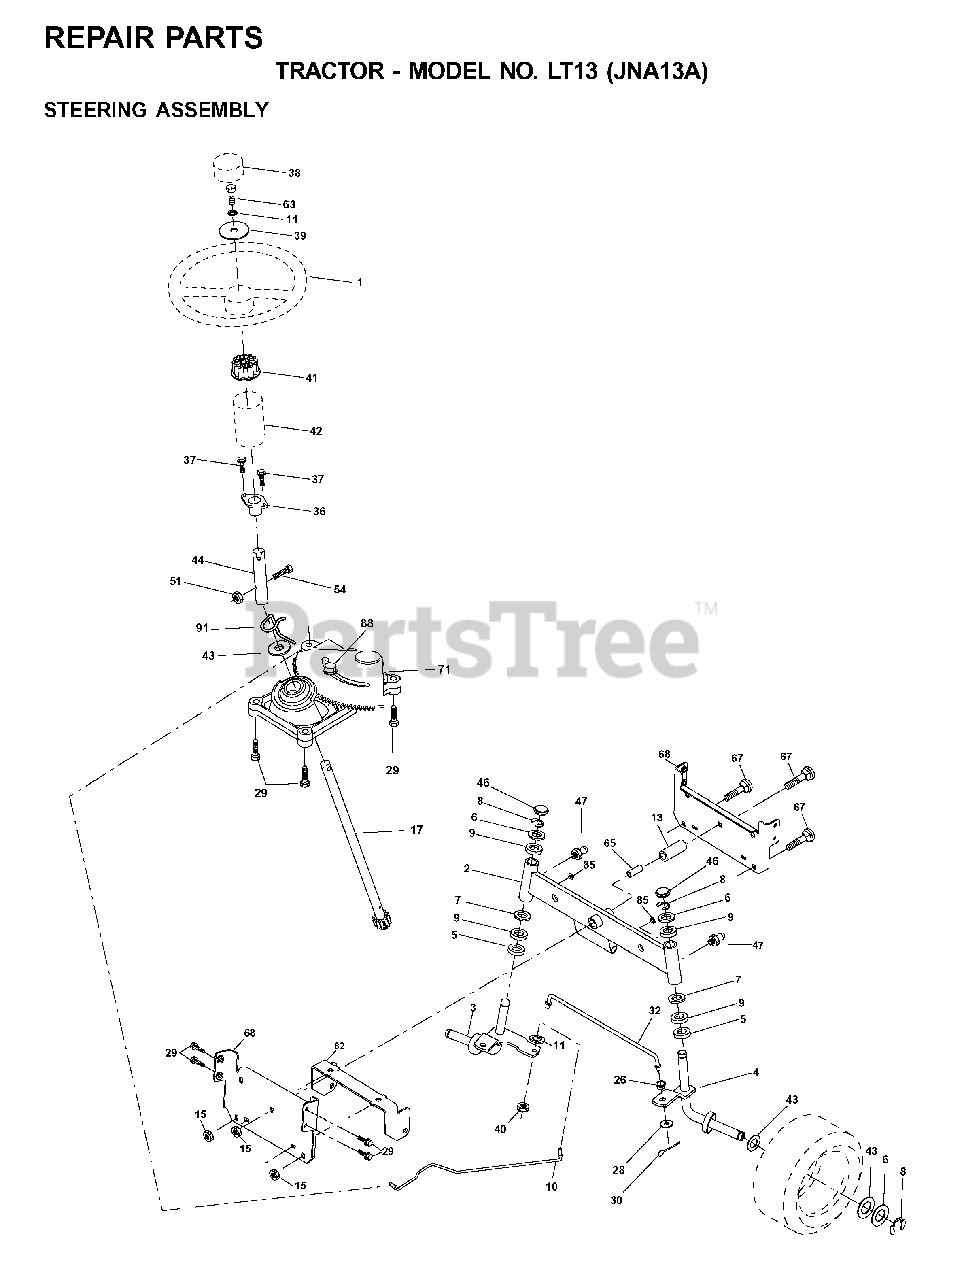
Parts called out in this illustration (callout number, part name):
2	AXLE ASSY
3	SPINDLE.ASM.LH.15"TIRES
4	SPINDLE.ASM.RH.15"TIRES
8	RING CLIP
9	BRNG T
10	DRAGLINK.15".TIRES.2001
11	WASHER, LOCK 3/8
13	TUBE, PIVOT AXLE
15	NUT
17	SHAFT ASM
26	BUSHING.DRAGLINK
28	WASHER
29	SCREW 3/8-16X3/4
30	COTTER PIN
32	TIE ROD
36	BUSHING, STEERING
39	WASHER 13/32 X 2-3/8 X 12GA
40	GRIPCO NUT
41	ADAPTER LT
42	BOOT.STEERING.SHAFT.BLACK
44	EXT SHAFT STEERING
46	CAP.SPINDLE
47	ZERK M
51	NUT.71038.31-18.HEX.NYLOCK
54	BOLT.5/16-18X1-1/4 FULL.THREAD
65	SPACER BRACE AXLE
67	BOLT
68	BRACE.AXLE.15"TIRES
71	STEERING ASM
82	BRACKET
85	FASTENER.XMAS.TREE
88	BOLT, SHOULDER 7/16-20
91	CLIP.STEERING
